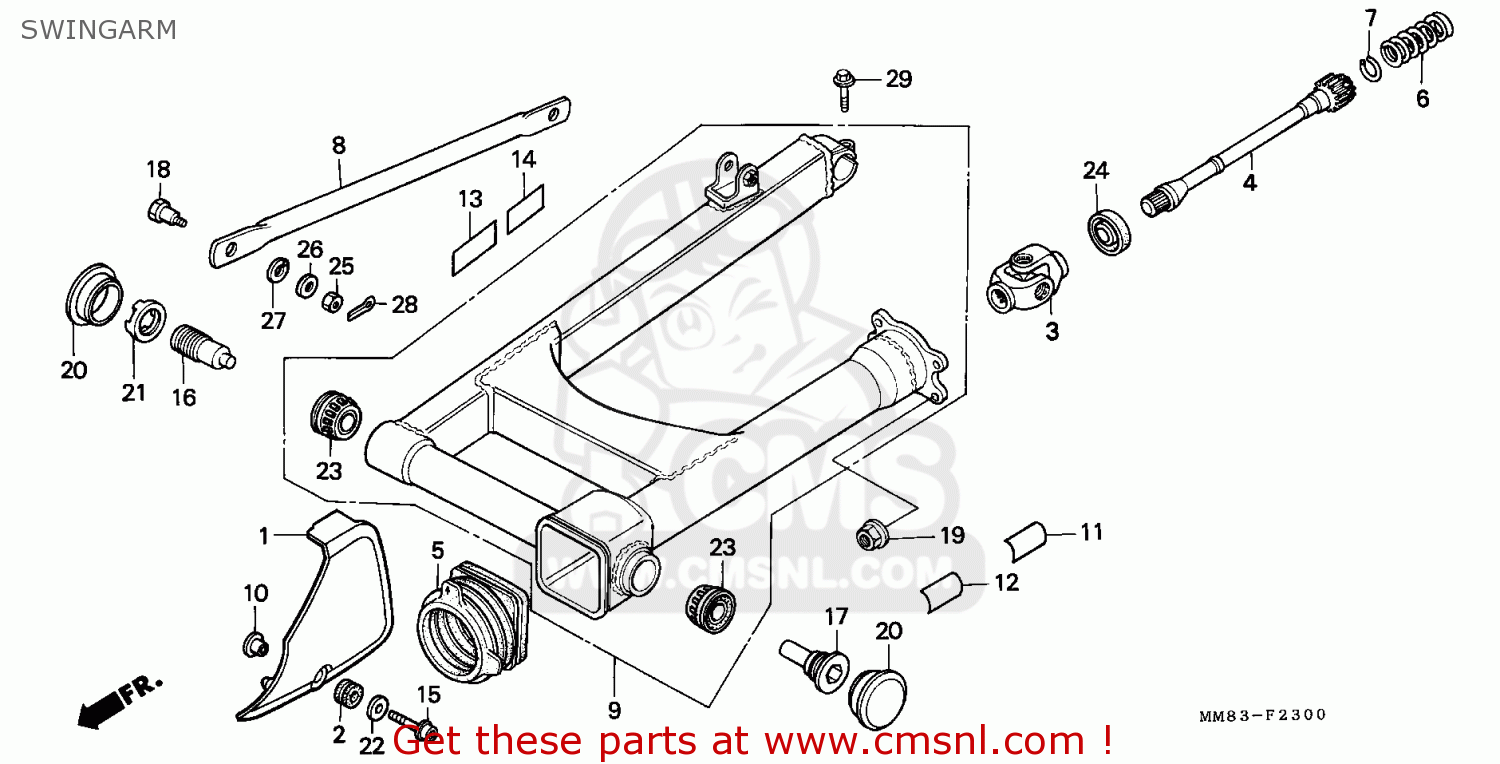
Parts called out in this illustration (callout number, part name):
1	COVER COMP,L REAR
2	RUBBER,CUSHION
3	JOINT COMP,YOKE
4	SHAFT,PROP.
5	BOOT,JOINT
6	SPRING,SHAFT
7	RING,STOPPER
8	ARM,RR.BRAKE STOP
9	ARM ASSY.,S*NH-1*
10	COLLAR,CHAINGUARD
12	LABEL,TIRE
14	LABEL,ACCESSORY L
15	BOLT,FLANGE,SOCKE
16	BOLT,R(RR.FORK) P
17	BOLT,L.RR.FORK
18	BOLT,STOPPER ARM
19	NUT,HEX.,10MM
20	CAP,R.LOCK NUT
21	NUT,RR.FORK PIVOT
22	WASH PLAIN 9MM
23	BRG,TAP.17X40X13.
24	OIL SEAL,27X43X7
26	WASHER,PLAIN,8MM
27	SPG-WASHER 10MM
28	PIN,COTTER 2.0X15
29	BOLT,FLANGE,8X32
